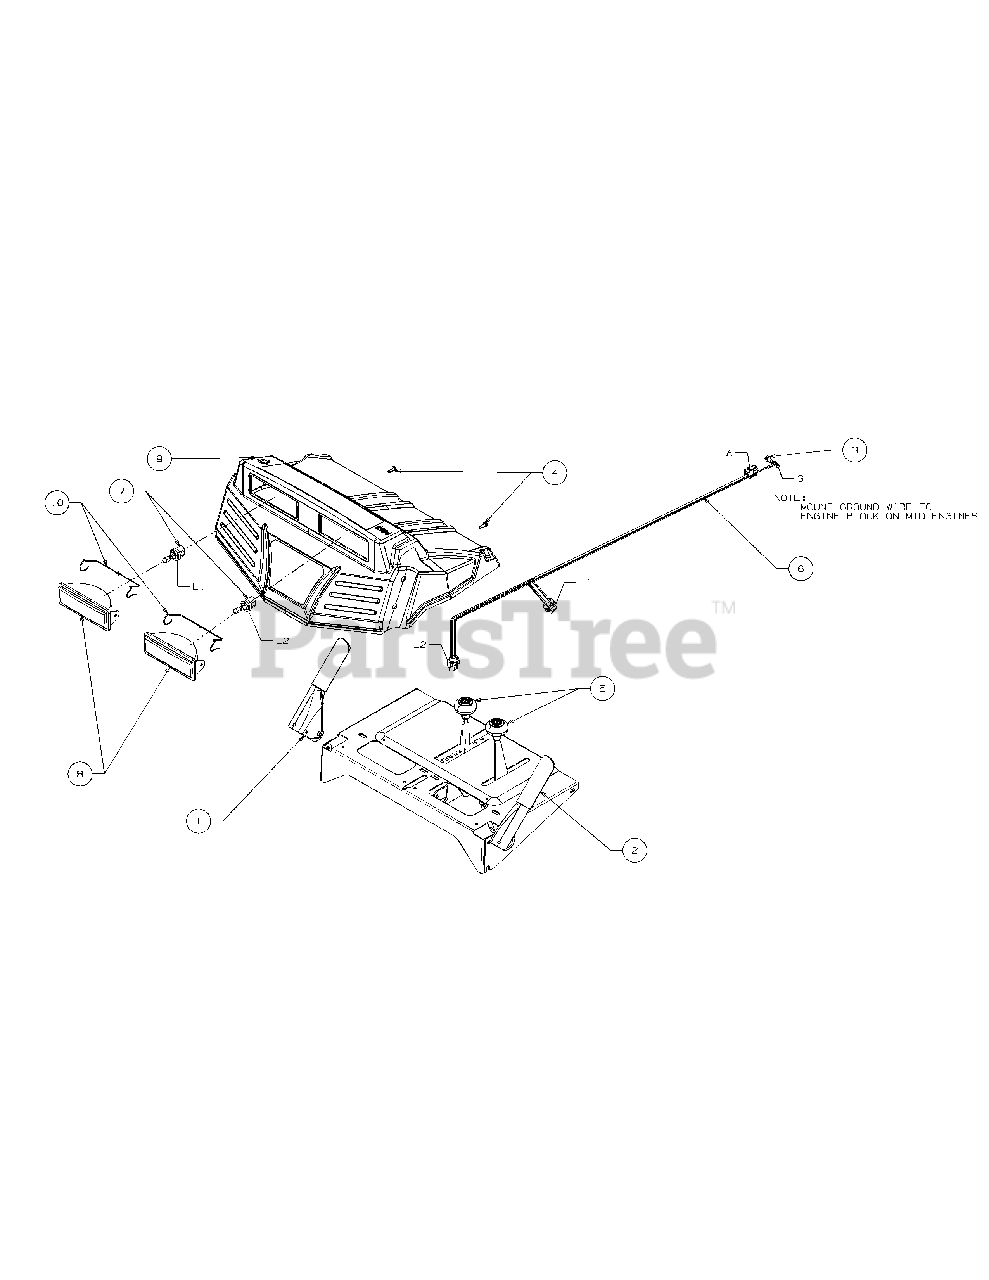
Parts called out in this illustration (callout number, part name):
1	Handle-Clutch RH
2	Handle-Clutch LH
3	Screw-Hex Wash Sf
4	Screw-B 10-16 X
5	Knob-Shift
6	Harness-Snow Dual
7	Bulb Halogen
8	Lamp Housing Wit
9	Panel-Handle 7 Style
10	Retainer
